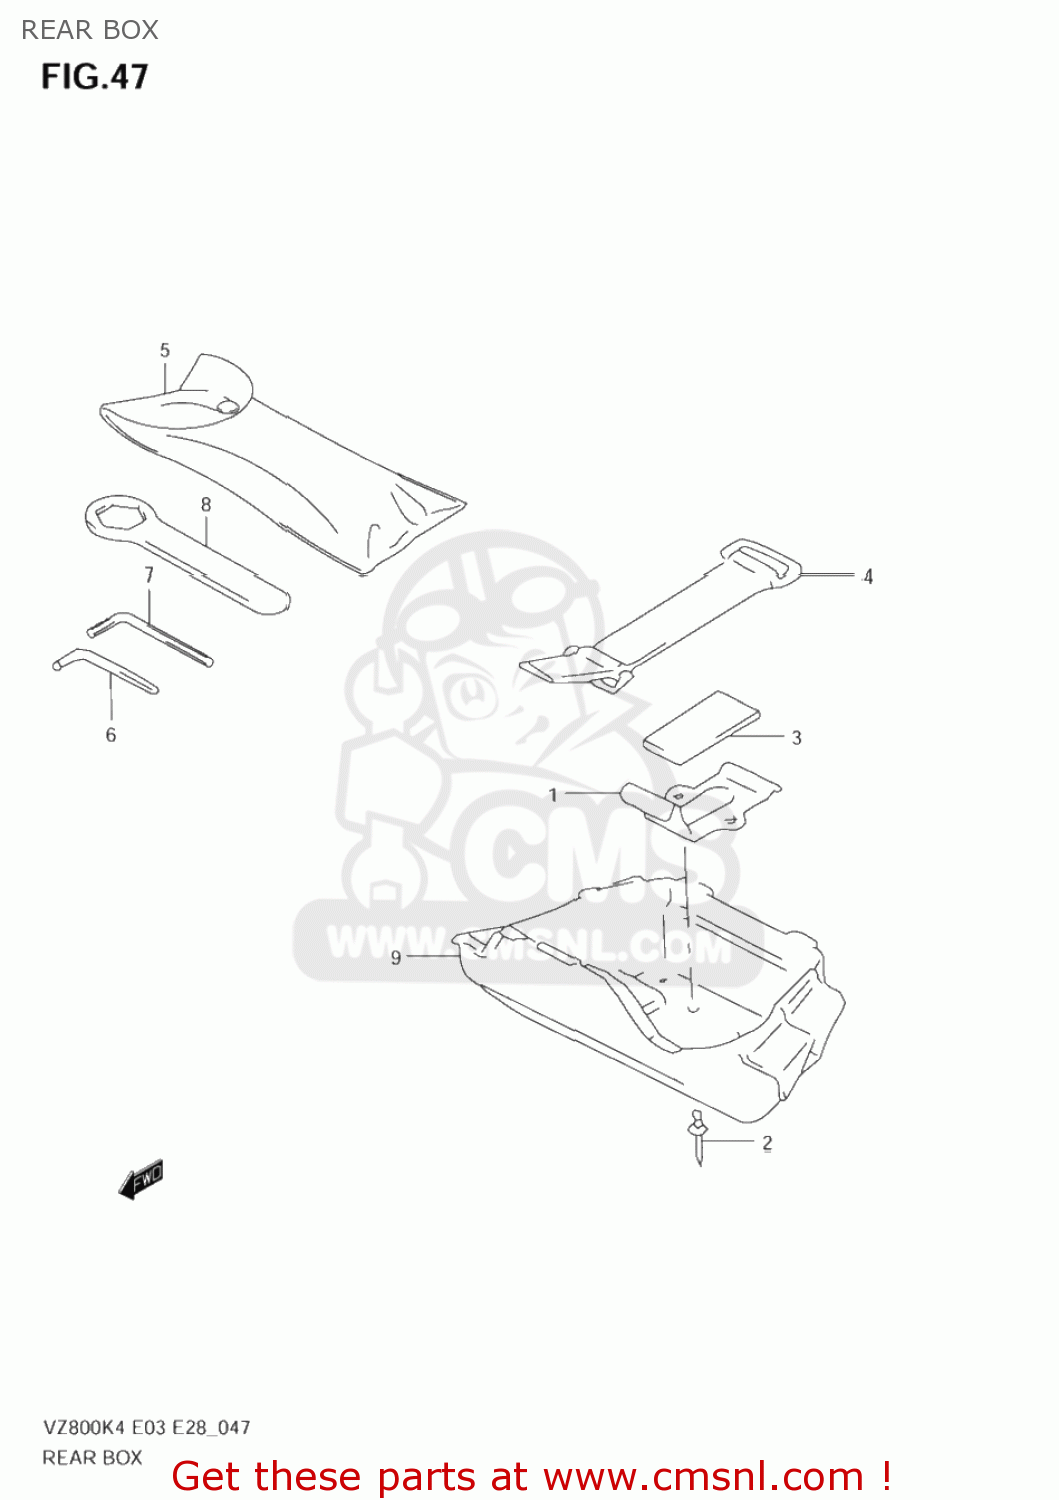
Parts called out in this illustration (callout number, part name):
1	HOLDER,TOOL
2	RIVET
3	PROTECTOR(170X95X3.0)
4	BAND,TOOL
5	TOOL ASSY
6	SPANNER,HEXAGON(4)
7	SPANNER,HEXAGON(6)
8	RING SPANNER(22)
9	BODY,LUGGAGE BOX
